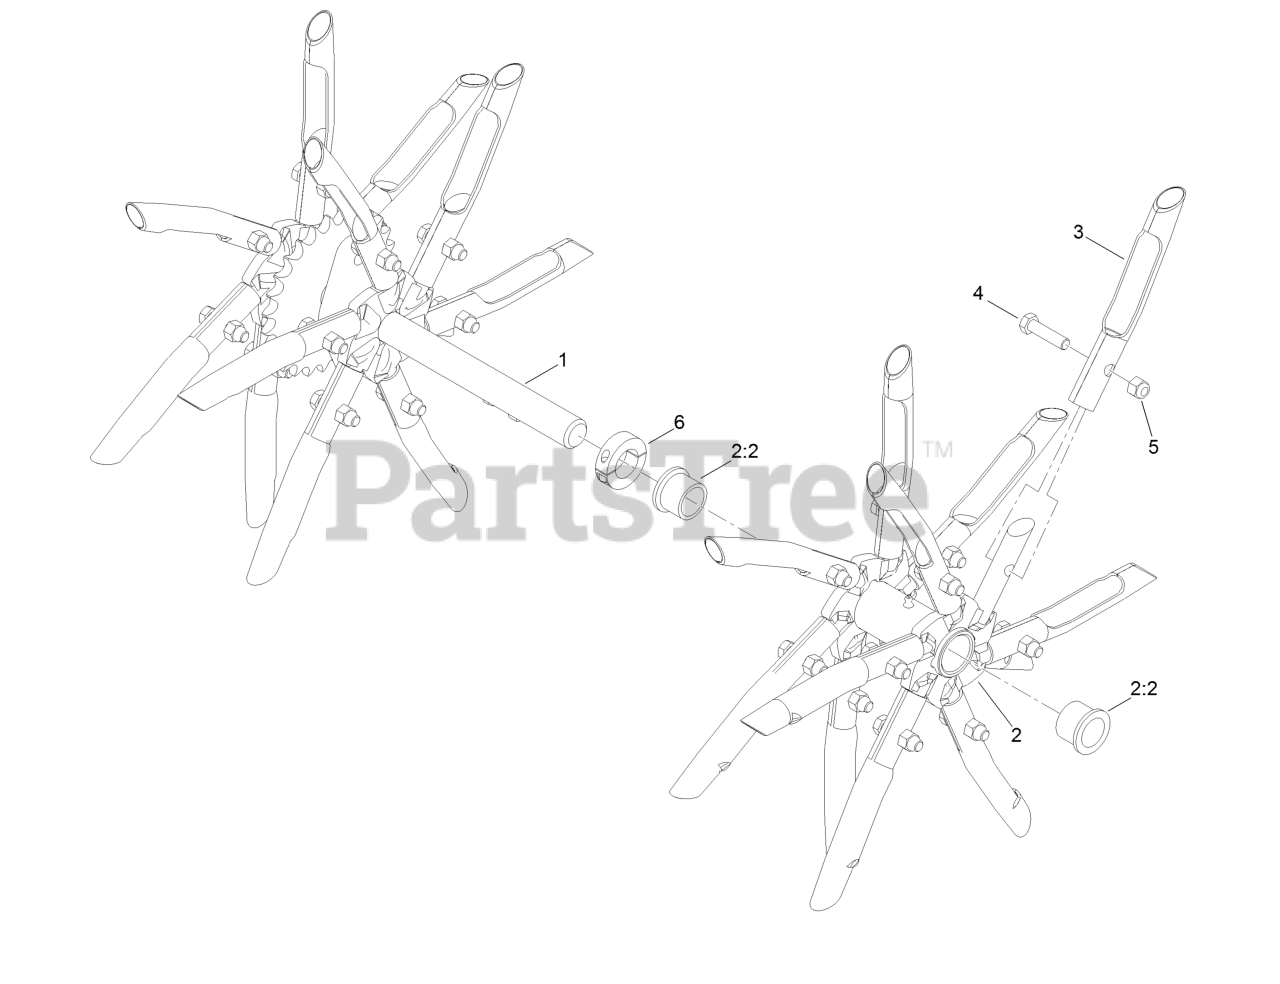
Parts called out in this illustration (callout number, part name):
1	Shaft-Tine, RH
2	Float Tine Shaft ASM
2:2	Bushing-Flange
3	Tine-Coring (3/4 Inch)
4	Screw-HH
5	Nut-Lock, NI
6	Collar-Locking
